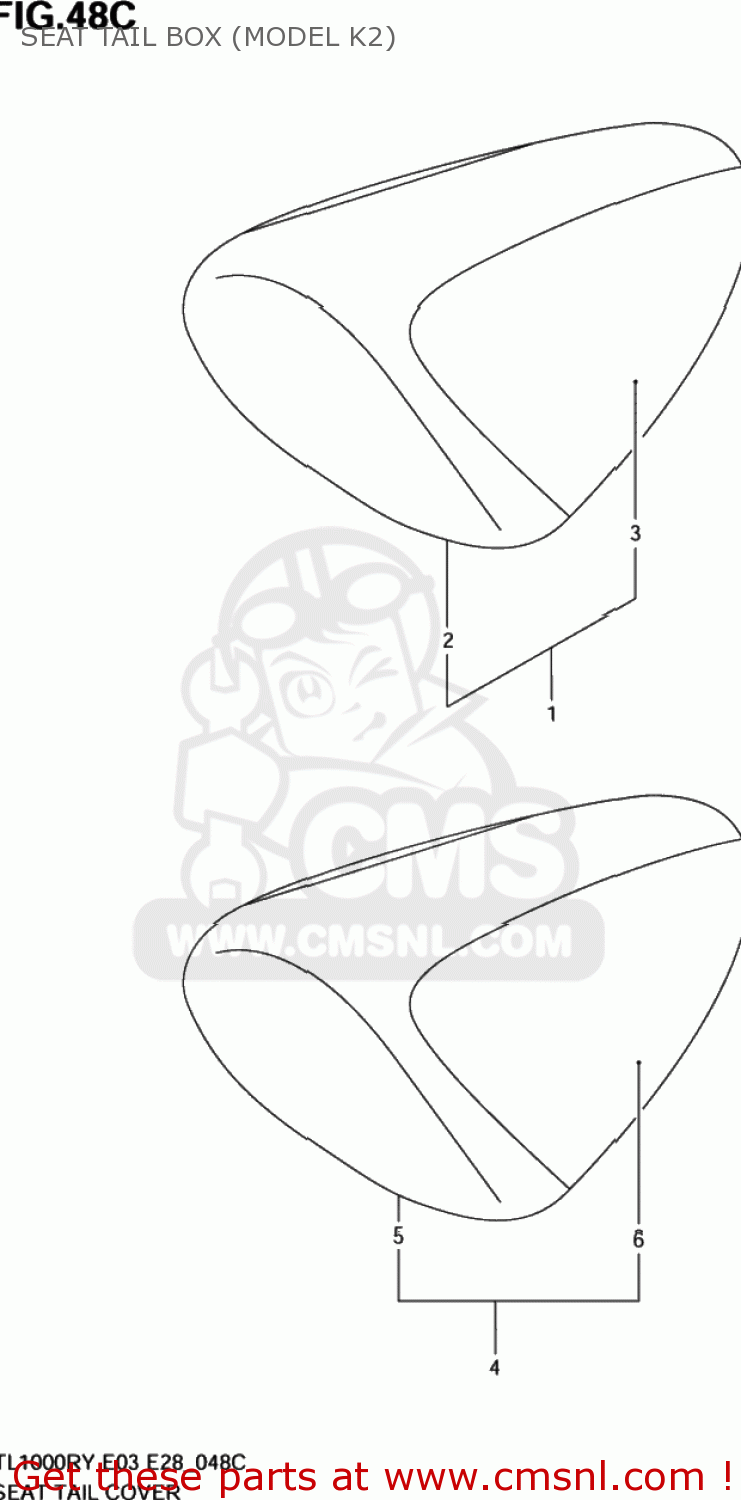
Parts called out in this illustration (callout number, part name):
1	BOX ASSY,SEAT TAIL(BLACK)
2	BOX,SEAT TAIL(BLACK)
3	TAPE SET,BOX SEAT TAIL(WHITE)
4	BOX ASSY,SEAT TAIL(YELLOW)
5	BOX,SEAT TAIL
6	TAPE SET,BOX SEAT TAIL(SILVER)
